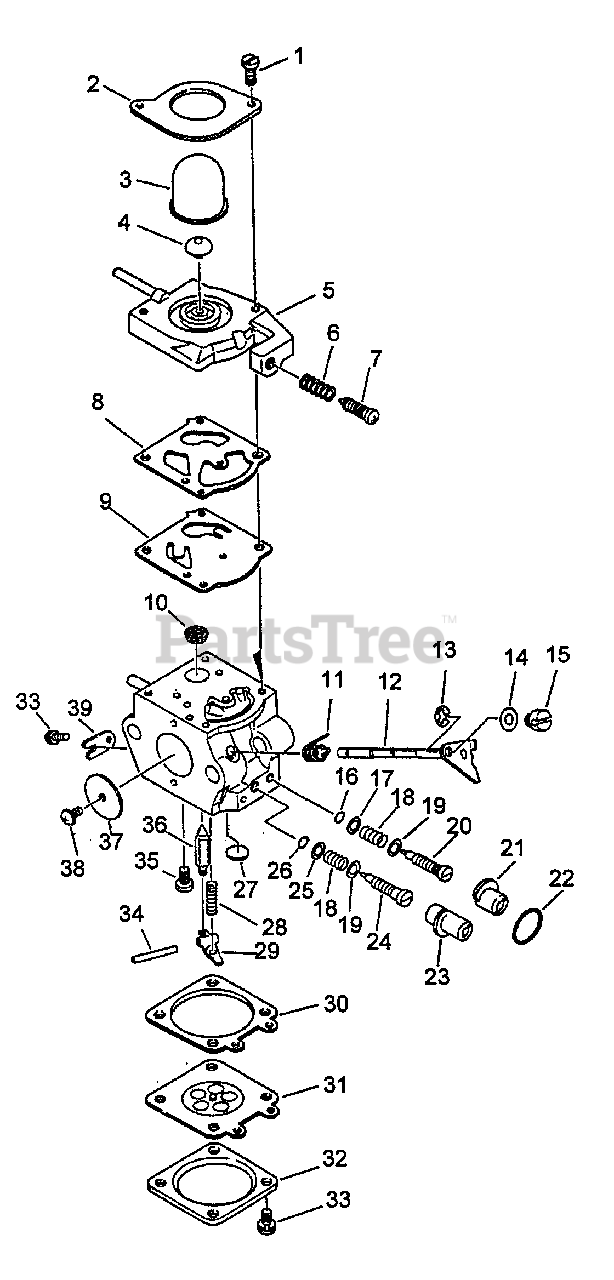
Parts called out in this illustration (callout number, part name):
2	RETAINER, PURGE BULB
3	BULB, PURGE
4	VALVE, CHECK
5	COVER, PUMP
6	SPRING, IDLE ADJUST
7	SCREW, IDLE ADJUST
8	GASKET, PURGE
9	DIAPHRAGM, PURGE
10	STRAINER
11	SPRING, THROTTLE RETURN
12	SHAFT, THROTTLE
13	RING, RETAINING
17	WASHER
18	SPRING
19	WASHER
20	NEEDLE - HIGH SPEED
21	CAP, LIMITER
22	O-RING
23	CAP, LIMITER
24	NEEDLE - LOW SPEED
25	WASHER
26	O-RING
27	PLUG, WELCH
28	SPRING, METERING LEVER
29	LEVER, METERING
30	GASKET, METERING
31	DIAPHRAGM, METERING
32	COVER, METERING
33	SCREW
34	PIN, METERING LEVER
35	SCREW, METERING LEVER PIN
36	VALVE, INLET NEEDLE
37	VALVE, THROTTLE
39	CLIP, THROTTLE SHAFT
